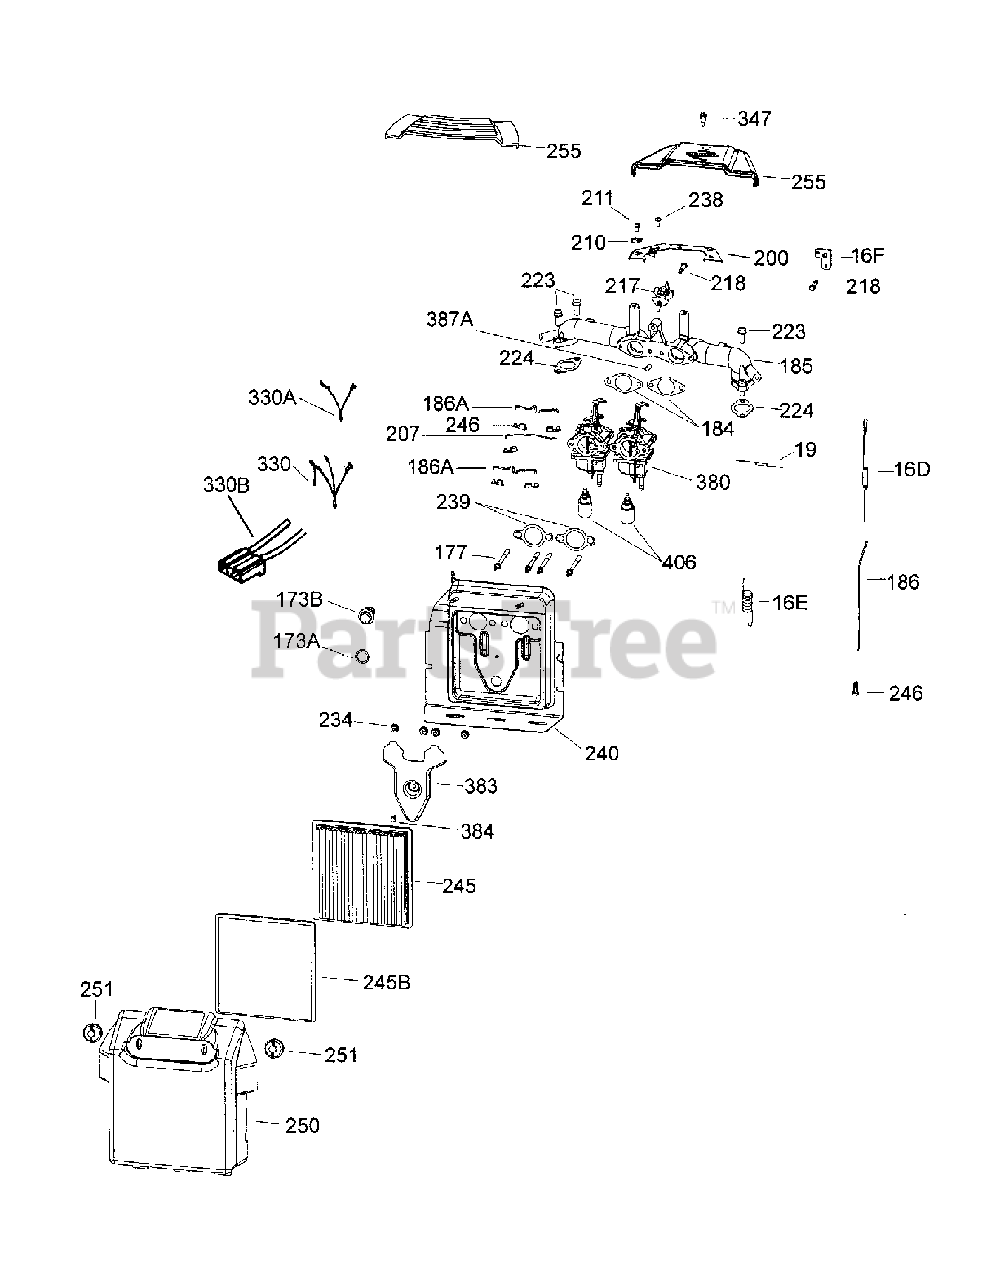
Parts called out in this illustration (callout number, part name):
11A	Breather Plate
11B	Screw, 10-32 x 7/16"
15	Governor Rod
15B	Screw, 1/4-20 x 5/8"
16	Governor Lever
16A	Governor Spring Bracket
16D	Governor Spring, Hi-speed
16E	Governor Idle Spring
16F	Bell Crank Lever
17C	Breather Tube Clamp
19	Throttle Spring
35	Screw, Carriage 1/4-20 x 1-1/2"
37	Lock Nut, 1/4-20
38	Retaining Ring
40	Piston, Pin & Ring Set (Std.)
40	Piston, Pin & Ring Set (.010"OS)
41	Piston & Pin Ass'y. (Std.) (Incl. 43)
41	Piston & Pin Ass'y.(.010"OS)(Incl.43)
42	Ring Set (Std.)
42	Ring Set (.010"OS)
43	Piston Pin Retaining Ring
45	Connecting Rod Ass'y. (Incl. 46)
46	Connecting Rod Bolt
48	Valve Lifter
50	Camshaft (MCR)
52	Oil Pump Ass'y.
52A	Oil Pump Shaft
52C	Oil Pump Cover (Incl. 52B)
52D	Screw, T-30 1/4-20 x 43/64"
52E	Oil Pump Gear
52F	Oil Pump Gear Retaining Ring
60A	Screw, 1/4-20 x 1/2"
69	Mounting Flange Gasket
70	Mounting Flange (Incl. 72,72A,75,80,381-387)
72	Oil Drain Plug, 3/18-18
72A	Oil Drain Plug, 3/8-18
72C	Oil Drain Valve
75	Oil Seal (1 in Ref 1, 1 in Ref 70)
75A	Oil Seal (Governor Shaft)
80	Governor Shaft
81	Washer (Governor Shaft)
82	Governor Gear Ass'y.
83	Governor Spool
84	Retaining Ring
86	Screw, 5/16-18 x 1-15/32"
90	Flywheel (Incl. 91 & 91A)
91A	Flywheel Retainer
92	Lock Washer, Flywheel (Under Ref. 93)
100	Solid State Ignition (Incl. 101)
101	Spark Plug Cover
102	Solid State Mounting Stud
103	Screw, T-15 10-24 x 15/16"
119	Cylinder Head Gasket
120	Cylinder Head, Opp. Breather Side
120A	Cylinder Head, Breather Side
125	Exhaust Valve (Std.)
126	Intake Valve (Std)
128	Belleville Washer
130	Screw, 5/16-18 x 2-1/2"(Head Mount)
135	Spark Plug (RN4C)
150	Valve Spring
151	Valve Keeper Retainer & Cap Set
153	Push Rod Guide
154	Rocker Arm Stud
159	Rocker Arm Cover Gasket
160	Rocker Arm Cover, Opp. Breather Side
160A	Rocker Arm Cover, Breather Side
161	Screw, T-30 1/4-20 x 1/2"
161A	Stud, Valve Cover Mounting
162	Rocker Arm Jam Nut, 5/16-24
163	Internal Lock Washer, 5/16"
169	Valve Cover Gasket
171	Breather Element
173	Breather Tube
173A	Breather Tube Grommet
173B	Breather Tube Fitting
177	Carbuertor Mounting Stud
184	Carburetor to Intake Pipe Gasket
185	Intake Pipe (Incl. 387A)
186	Governor Link
200	Control Bracket
207	Throttle Link
210	Conduit Clip
211	Screw, 10-32 x 3/8"
217	Control Lever
218	Screw, 10-32 x 1-1/4"
223	Screw, T-30 5/16-18 x 7/8"
224	Intake Pipe Gasket (Pipe to Head)
234	Lock Nut, 1/4-20
238	Screw, 10-32 x 7/16"
239	Air Cleaner Gasket
240	Air Cleaner Body Ass'y. (Incl. 239)
245	Air Cleaner Filter (Paper)
245B	Air Cleaner Pre-Filter (Poly)
246	Connector Bushing Link
250	Air Cleaner Cover
251	Wing Nut, 1/4-20 X 1-19/32" (A/C)
253	Compression Release Weight
253A	Compression Release Pin
254	Compression Release Spring
255	Control Cover
260	Blower Housing (Red)
261	Screw, 1/4-20 x 1/2"
265	Cylinder Head Cover, Opp. Breather
265A	Cylinder Head Cover, Breather Side
270A	Exhaust Port Liner
286	Flywheel Screen
287	Screw, T-20 8-18 x 1-15/32"
290	Fuel Line (17")
291	Fuel Line (8-1/4")
291A	Fuel Line (8-1/4")
291B	Fuel Line (8-1/4")
291C	Fuel Line (6-3/4")
292	Fuel Line Clamp
292A	Fuel Line Retainer
293A	Screw, 8-32 x 1-1/2"
294	Pulse Pump Repair Kit
295A	Fuel Fitting
296	Fuel Filter (Incl. 292)
303	Pulse Pump/Fuel Fitting
305	Oil Fill Tube
306	O-Ring (Oil Fill, Bottom)
307	O-Ring Oil Fill,(Top)
309	Screw, 1/4-20 x 57/64"
315	Alternator Coil (3/5 Split) (Incl.321- 323)
322	Connector Body
330	Wire Harness, Twin-Solenoid (Red), and Ignition Ground (Green)
330A	Twin-Solenoid Ground Wire (Black)
342	Screw, 1/4-20 x 9/16"(Ref. 240 & 265)
346	Fuel Pump Bracket
347	Screw, 10-32 x 27/32"
361	Screw, 5/16-18 x 2-3/8"
370A	Lubrication Decal
380	Carburetor (Incl. 184 & 428)
381	Screw, 8-32 x 27/64"
382	Oil Strainer Screen
383	Carburetor Baffle
384	Screw, 10-24 x 9/16" Self Tap
386	Pressure Release Spring
395	Electric Starter Motor (12 Volt)
400	Gasket Set (Incl. Items Marked PK in Notes)
406	Fuel Shut-Off Solenoid
476	Oil Filter Adaptor (Incl. 479)
477	Screw, T-30 5/16-18 x 1 3/32"
479	Oil Filter Adaptor Gasket
